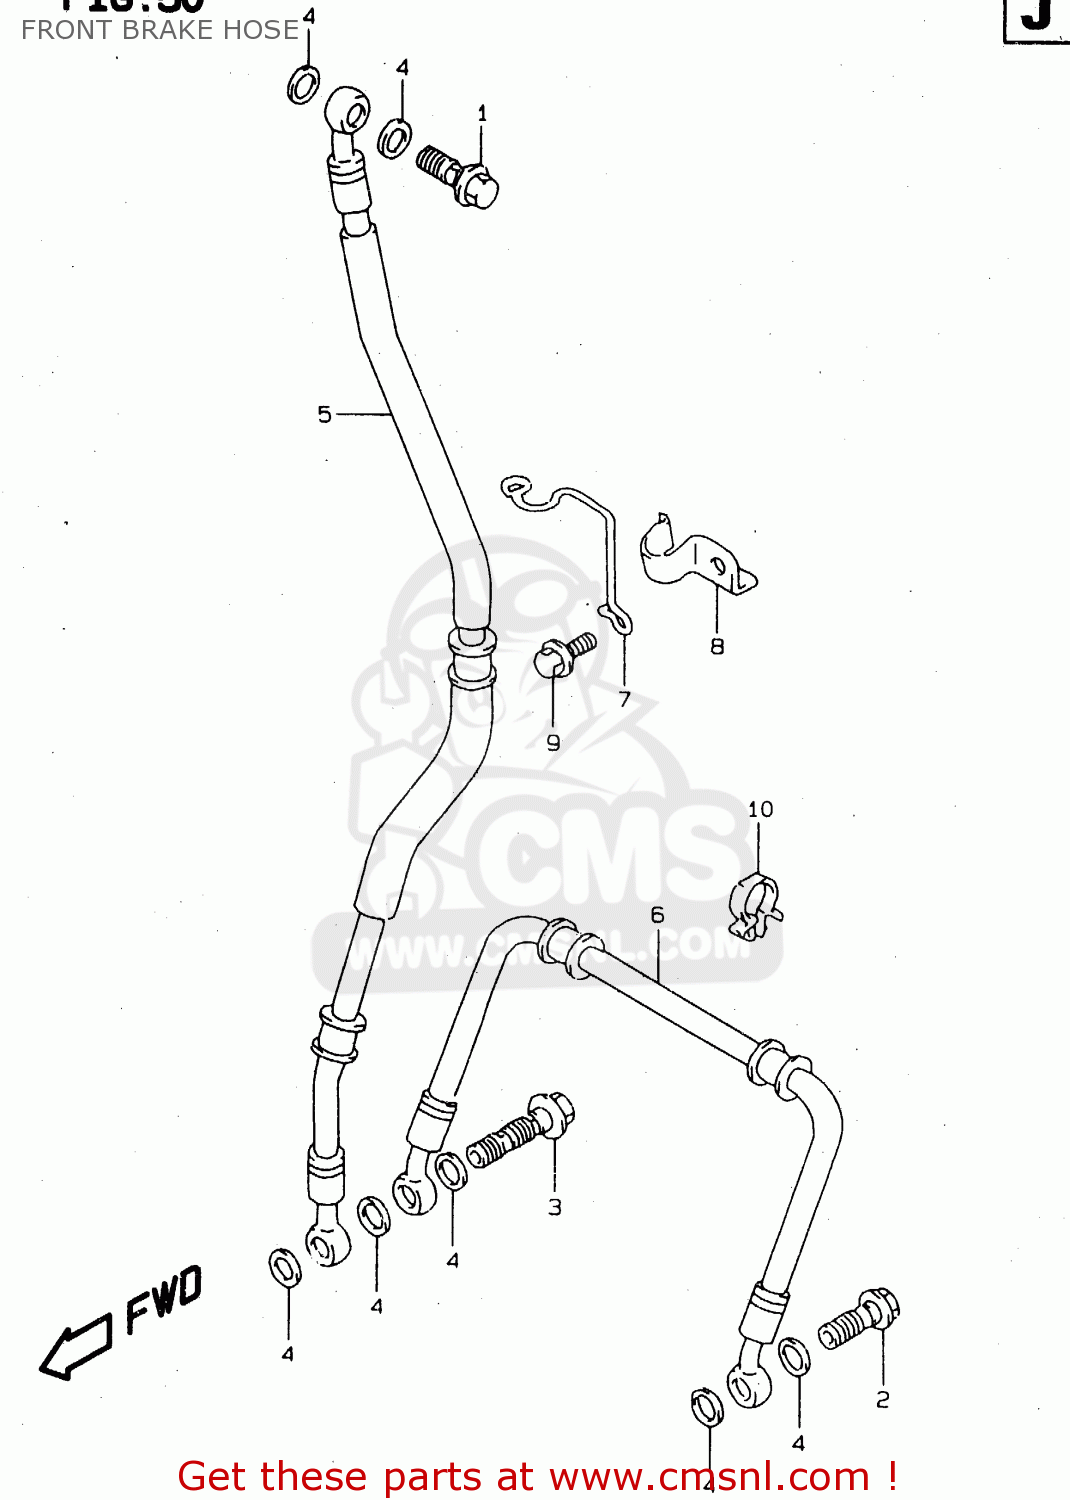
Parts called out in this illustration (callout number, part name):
1	BOLT UNION
2	BOLT UNION
3	BOLT UNION
4	WASHER(10X15X1.5)
5	HOSE,FR BRAKE NO.1
6	HOSE,FR BRAKE NO.2
7	GUIDE,FRONT BRAKE HOSE
8	CLAMP,FR BRAKE HOSE UPR
9	BOLT
10	CLAMP
